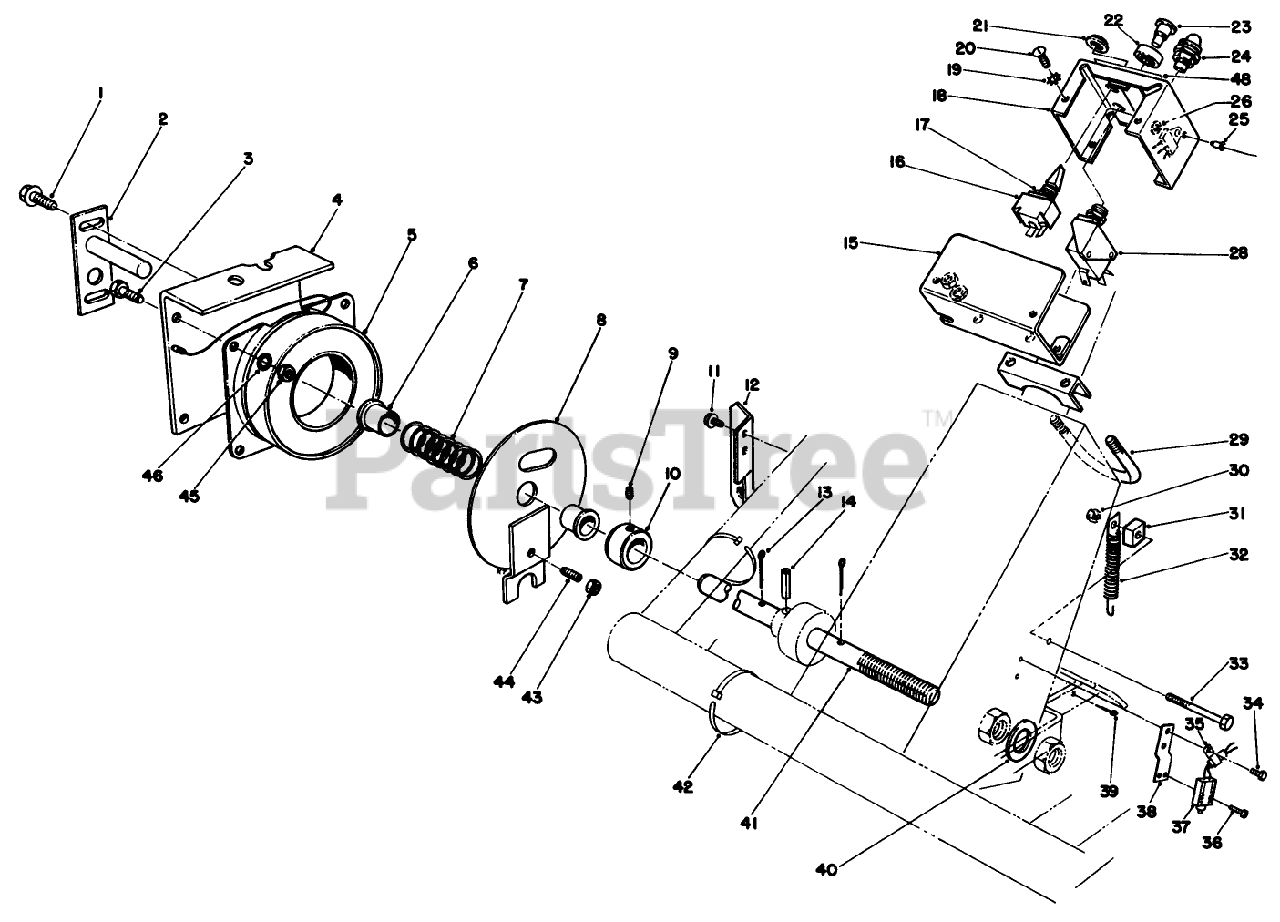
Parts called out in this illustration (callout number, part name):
1	SCREW-HHF
2	Shaft
3	SCREW-HH
4	BRACKET R
5	CORE-FIELD, COIL
6	BUSHING-FLANGE
7	SPRING-COMPRESSION
8	Clutch Plate
9	SCREW-HSH
10	Collar (Incl. Ref. #9)
11	SCREW-HWHTF
12	HOSE BRACKET B
13	PIN-COTTER
14	PIN-SPRING
15	HOUSING WA B
16	Switch Assembly (Incl. Ref. #17 & 21)
17	NUT-LOCK
18	BOX COVER WA B
19	WASHER-LOCK/EXT
20	SCREW-PPH
21	NUT-BULB
22	BEZEL
23	BUTTON-PUSH
24	Light-Warning
26	WASHER
28	Switch
29	MUFFLER CLAMP
30	NUT-LOCK, NI
31	IDLER SPACER
32	EXT SPRING ASM
33	SCREW-HH
34	Screw-Hex Flange Hd.
35	CLIP-CLOSED, INSULATED
36	SCREW-PPH
37	SWITCH
38	SWITCH BRACKET
39	PIN-COTTER
40	SPACER
41	SHAFT-TRACTION PEDAL
42	TIE-CABLE
43	NUT-HEX
44	SCREW-HSH
45	NUT-HEX
46	WASHER-LOCK
48	SPEED CONTROL DECAL
